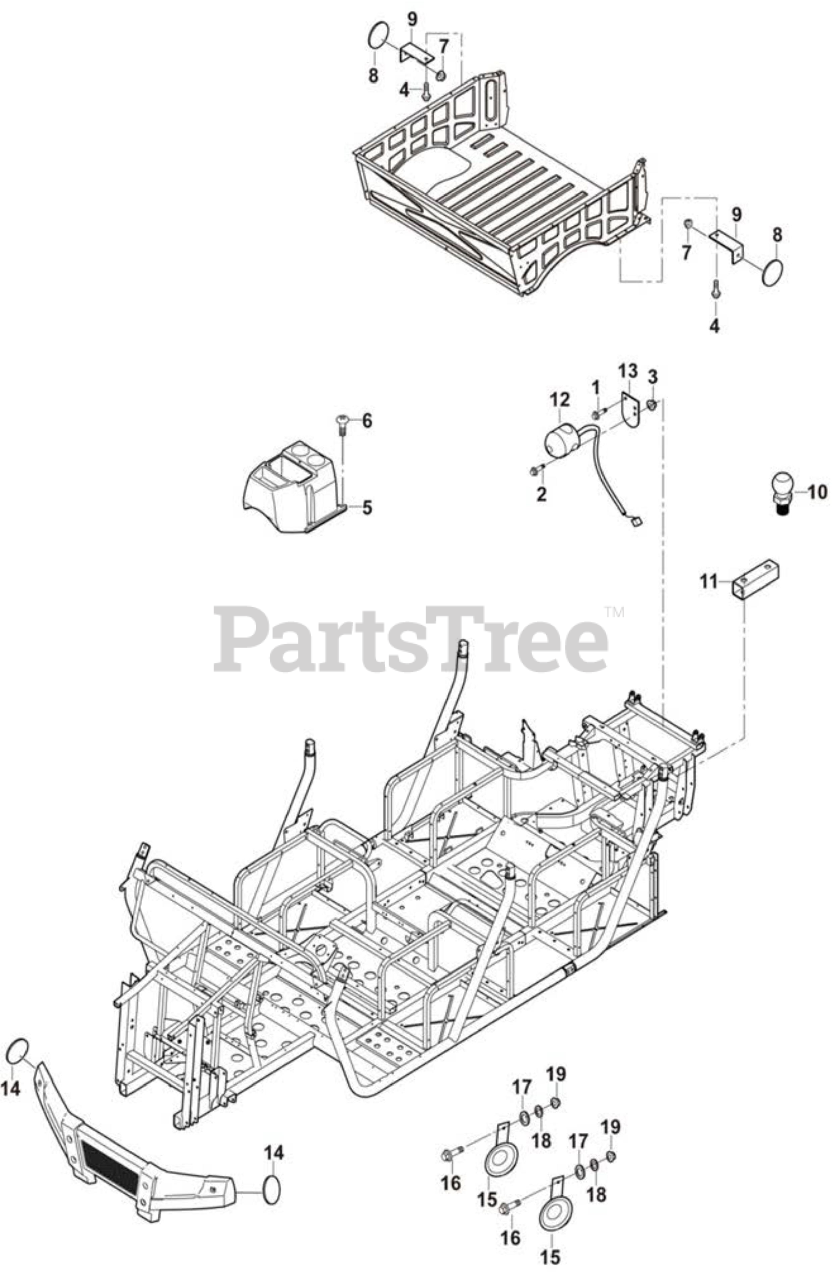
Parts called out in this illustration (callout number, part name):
1	Hexagon Flange Bolt M6X16
2	Cross Plate Head Screw M5X30
3	Hexagon Flange nut M5
4	Cross Large Plate Head Screw M6X12
5	Sundry Box
6	Pan head screw with cross recess M6X30
7	Hexagon Flange Nut M6
8	Side Reflector Assy (Red)
9	Mounting Plate,Rear Reflector
10	Hitch Bar Assy A
11	Rear Hitch Bar G
11	Rear Hitch Bar E
11	Rear Hitch Bar D
11	Rear Hitch Bar F
12	Trailer Plug Assy
13	Mounting Plate,Trailer Plug
14	Side Reflector Assy (Yellow)
15	Horn Assy.
16	Hexagon Flange Bolt M6X16
18	Spring Washer 6
19	Hexagon Flange Nut M6
